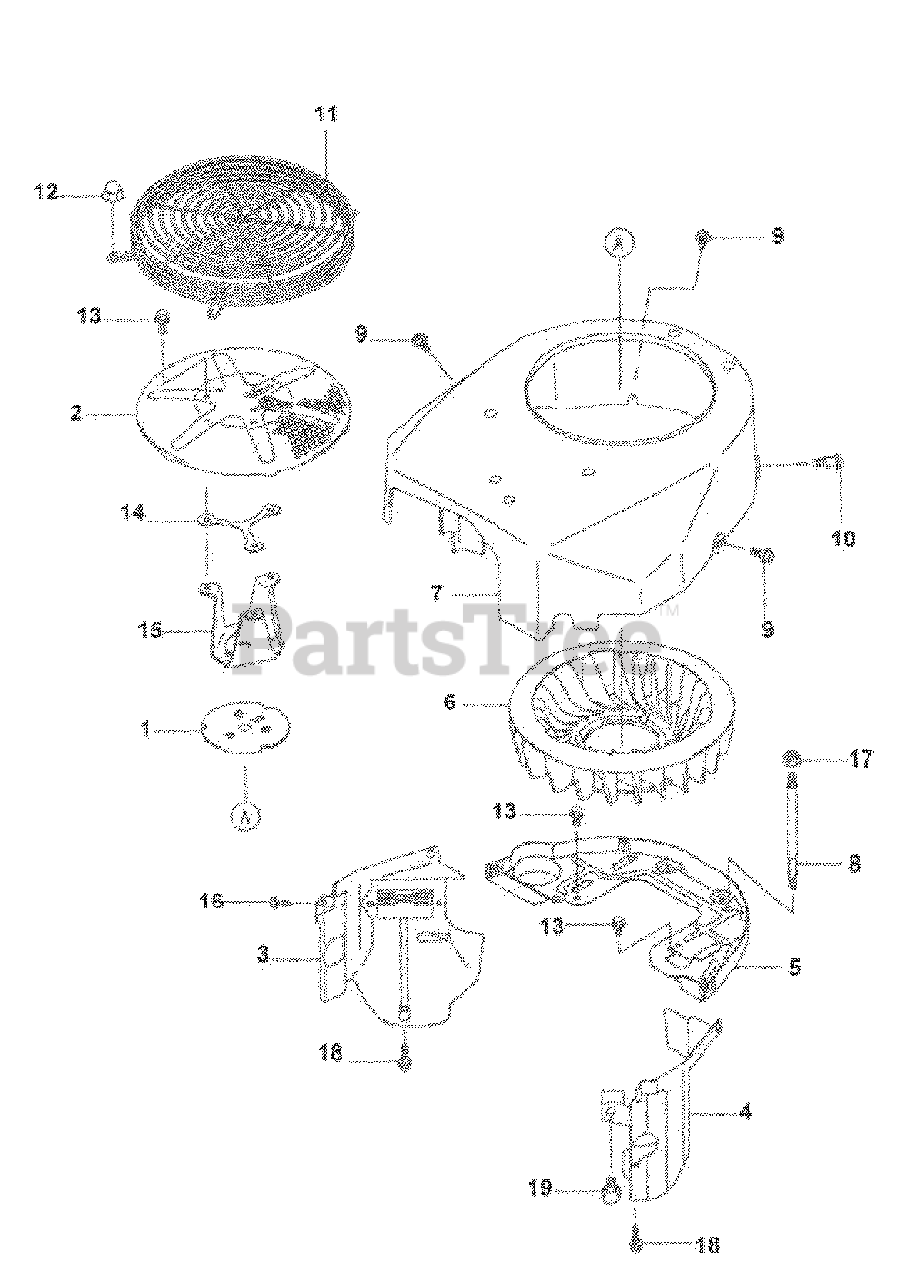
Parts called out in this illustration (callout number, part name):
2	Screen
3	Engine Shroud
4	Engine Shroud
5	Engine Shroud
6	Fan
8	Stud
10	Bolt
13	Flange Bolt
16	Flange Bolt
17	Hex Nut
18	Flange Bolt
19	Flange Bolt
